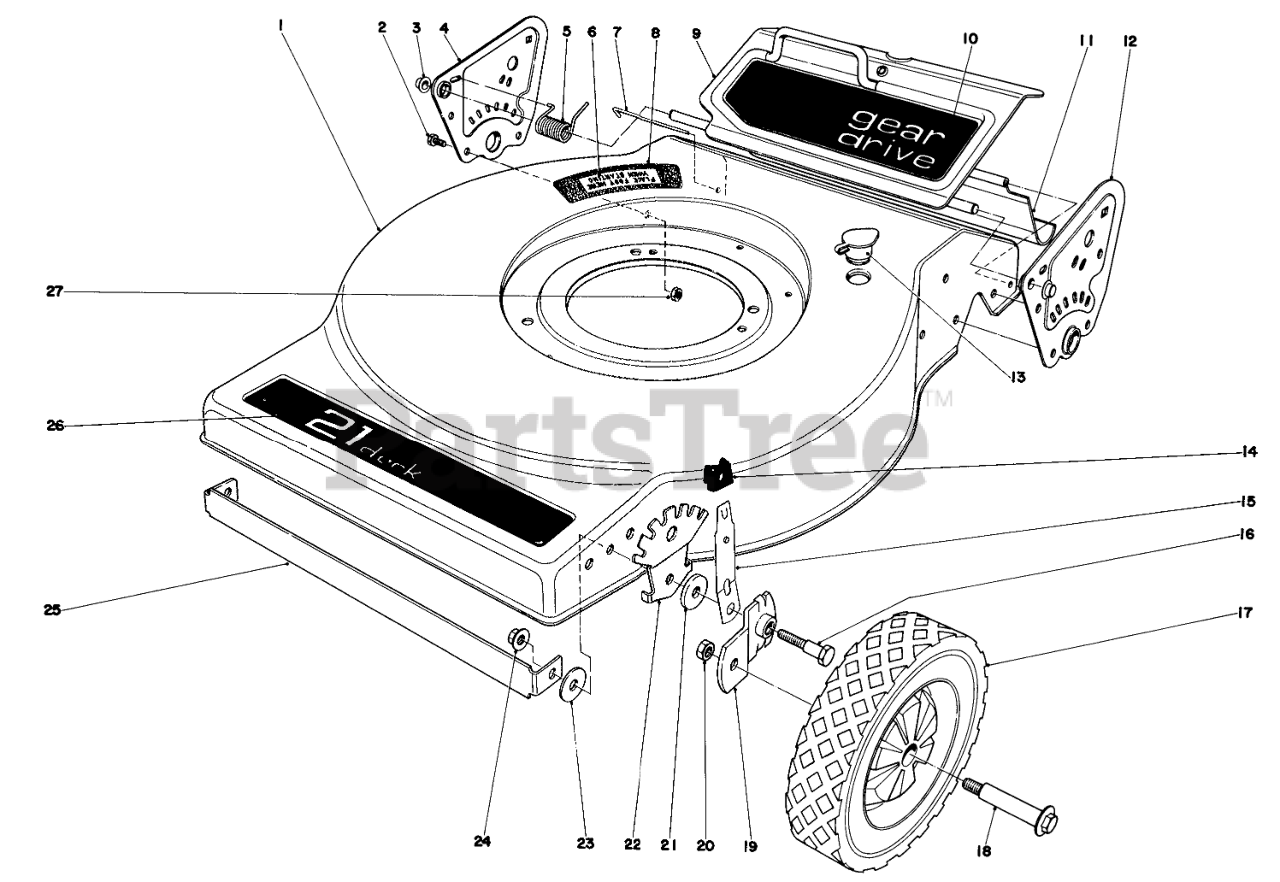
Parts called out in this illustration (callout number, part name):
1	Housing
2	SCREW-HH
3	RETAINER-PUSH ON
4	Side Plate R.H
5	TORSION SPRING
6	Decal Step Pad
7	SHIELD ROD
8	PAD STEP
9	Rear Door
10	Decal Door
11	SAF SHIELD REAR
12	Side Plate L.H.
13	WASHOUT PLUG
14	KNOB-ARM
15	SPRING ARM ASM
16	PIVOT SCREW
17	WHEEL TIRE ASM 8 IN
18	BOLT-WHEEL
19	PIVOT ARM ASM A
20	Nut
21	PIVOT WASHER
22	Quadrant
23	WASHER
25	DECK SUPPORT
26	Decal Deck
27	NUT-LOCK, CONE
